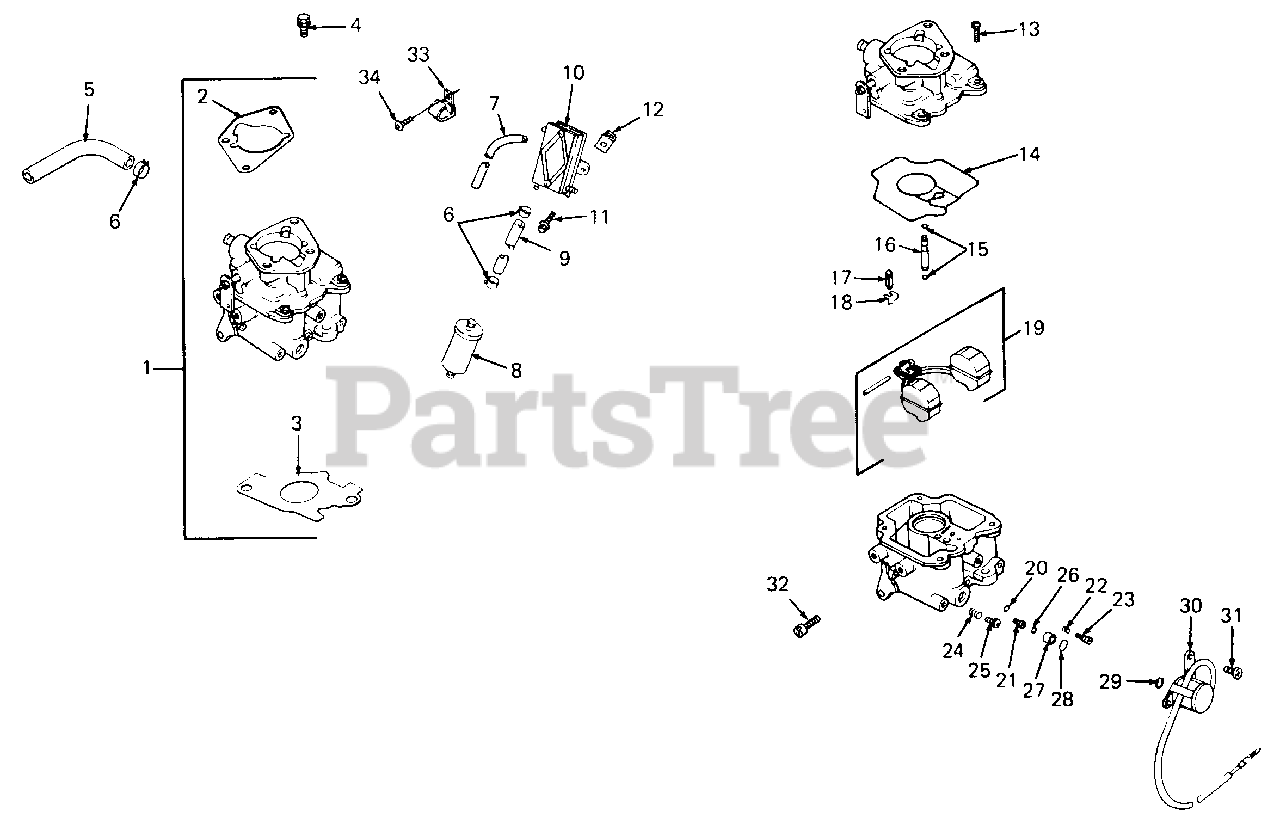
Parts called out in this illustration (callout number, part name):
1	Kit, Carburetor
2	Gasket, Air Cleaner
3	Gasket, Carburetor
4	Screw, M6 X 1.0 X 18
5	Line, Fuel, 9"
6	Clamp, Hose
7	Line, Fuel 15.5
8	Filter, Fuel
9	Line, Fuel, 10
10	Pump, Fuel-Pulse
11	Screw, Hex Cap
12	Nut
13	Screw, Carburetor Body
14	Gasket, Carburetor Body
15	O-Ring, Slow Jet
17	Valve, Inlet Needle
18	Clip, Inlet Needle Valve
19	Kit, Float Repair
20	O-Ring, Main Jet
22	Spring, Idle Adjust
23	Needle, Idle Adjust
24	Spring, Idle Speed Adjust
25	Screw, Idle Speed Adjust
27	Seat, Solenoid
29	O-Ring, Solenoid
30	Solenoid
32	Screw, Throttle Stop
33	Clip, Cable 1
34	Screw, M6 X 1.0 X 10
